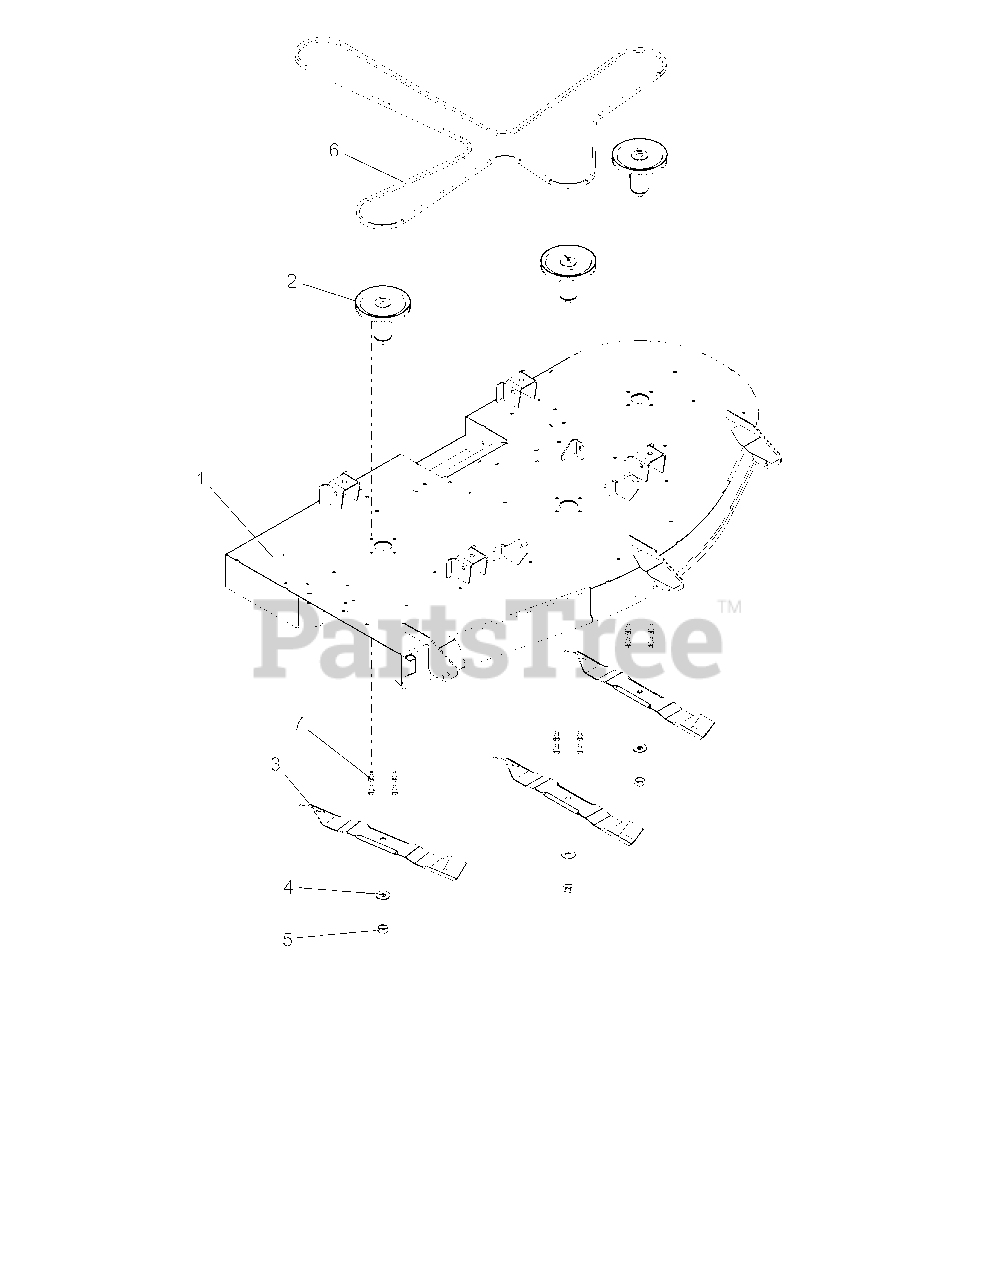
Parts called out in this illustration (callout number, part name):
1	KIT, 60" GRAVELY DECK W/DECALS
2	KIT, DECK SPINDLE ASM-60
3	BLADE, 21" 35 DEG
4	WSHR-BLVL .669X1.535X.138
5	NUT-STD .625-18 ZCC
6	BELT, HA
7	SCR,TAP .375-16X.75 HWH TR ZCC
